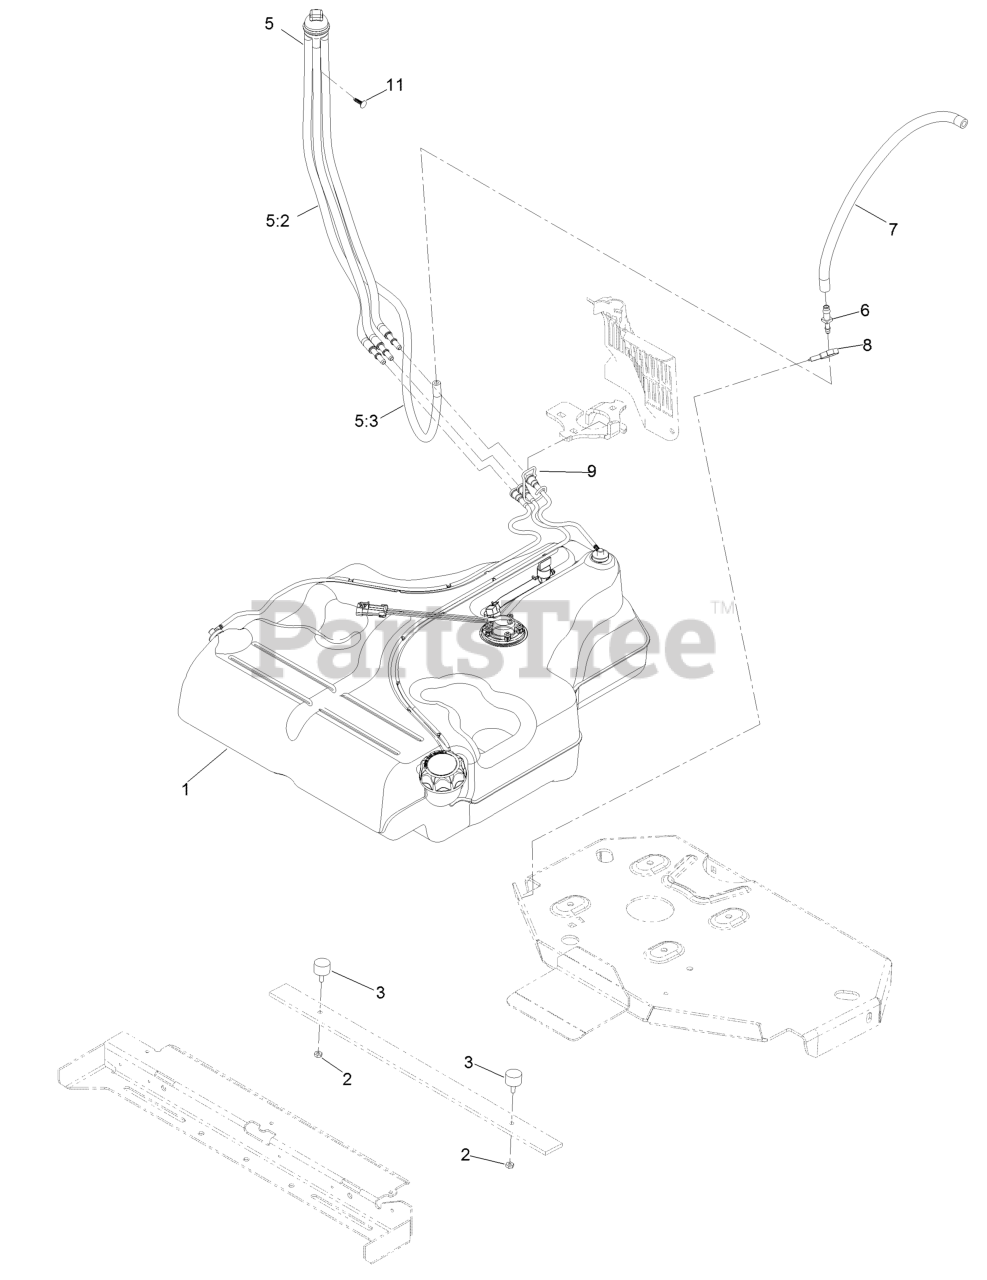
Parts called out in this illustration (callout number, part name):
1	Fuel Tank ASM
2	Nut-Jam
5	Fuel Manifold Vent ASM
5:2	Hose-Fuel
5:3	Hose-Fuel
6	Fitting-Straight
7	Hose-Fuel
8	Clamp-Hose
9	Retainer-Line, Vapor
11	Plug-Plastic
